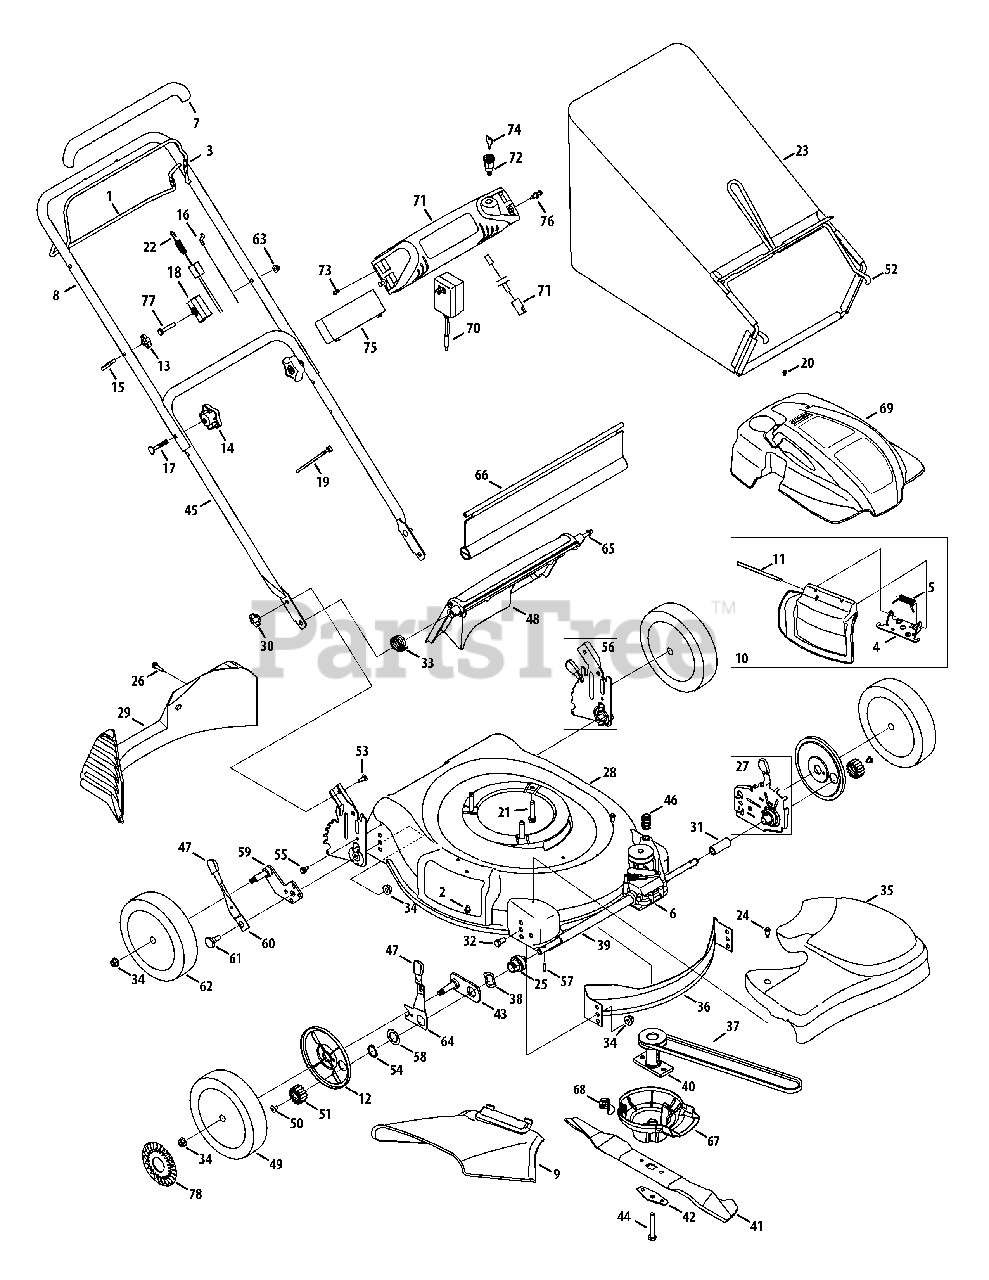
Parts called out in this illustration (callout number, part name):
1	Drive Control
3	Blade Control
4	Deflector Chute Adapter
5	Torsion Spring
6	Transmission Assembly
7	Blade Control Cover
9	Chute Deflector
10	Mulch Plug Complete
12	Wheel Dust Cap
13	Handle Knob
16	Control Cable 37.5"
17	Carriage Bolt 5/16-18 x 2.0
18	Control Cable Mount
19	Cable Tie
20	Screw, HL, #12-16 x 1.00
21	Self-Tapping Sems Screw
22	Drive Cable 21"
23	Grass Bag
24	Shoulder Screw # 12 -24
25	Front Bearing Assembly
26	Screw, 1/4-15 x 1.000
27	Height Adjustment Ass’y - RH
27	Height Adjustment Ass’y - LH
31	Slev. Spacer 1.4" Lg.
32	Hex Screw, 3/8-16 x.75
33	Torsion Spring - RH
34	Flange Lock Nut, 3/8-16
35	Transmission Cover
36	Front Baffle
38	Wave Washer
39	Sleeve Spacer 8.985" Lg.
40	One Piece Blade Adapter
41	21" Mulching Blade
42	Blade Bell Support
43	Pivot Plate Assembly
44	Hex Screw 3/8-24 x 2.50
46	Belt Tension Spring
47	Adjustment Knob
48	Rear Discharge Door
49	Front Wheel
50	Screw, 1/4-20 x .390
51	Gear 14T RH FWD
51	Gear 14T LH FWD
52	Grass Bag Frame
53	Carriage Bolt 1/4-20
54	Snap Ring
55	TT Scr. w/Washer 1/4-20 x.625
56	Handle Bracket Assembly - RH
56	Handle Bracket Assembly - LH
57	Dowel Pin
59	Pivot Arm Assembly - RH
59	Pivot Arm Assembly - LH
60	Rear Spring Lever
61	Shoulder Scr.500 Dia. x.434
63	Nut, Flglk, 1/4-20
64	Front Lever - RH
64	Front Lever - LH
66	Rear Trailing Shield
67	Engine Baffle
68	Engine Baffle Bracket
69	Engine Shroud
70	Battery Charger
70	Battery Charger (w/LED Light)
71	Electric Start Harness Assembly
72	Key Switch
73	Screw, #10-16 x .750
75	Battery
77	Screw, 1/4-20 x 1.50
